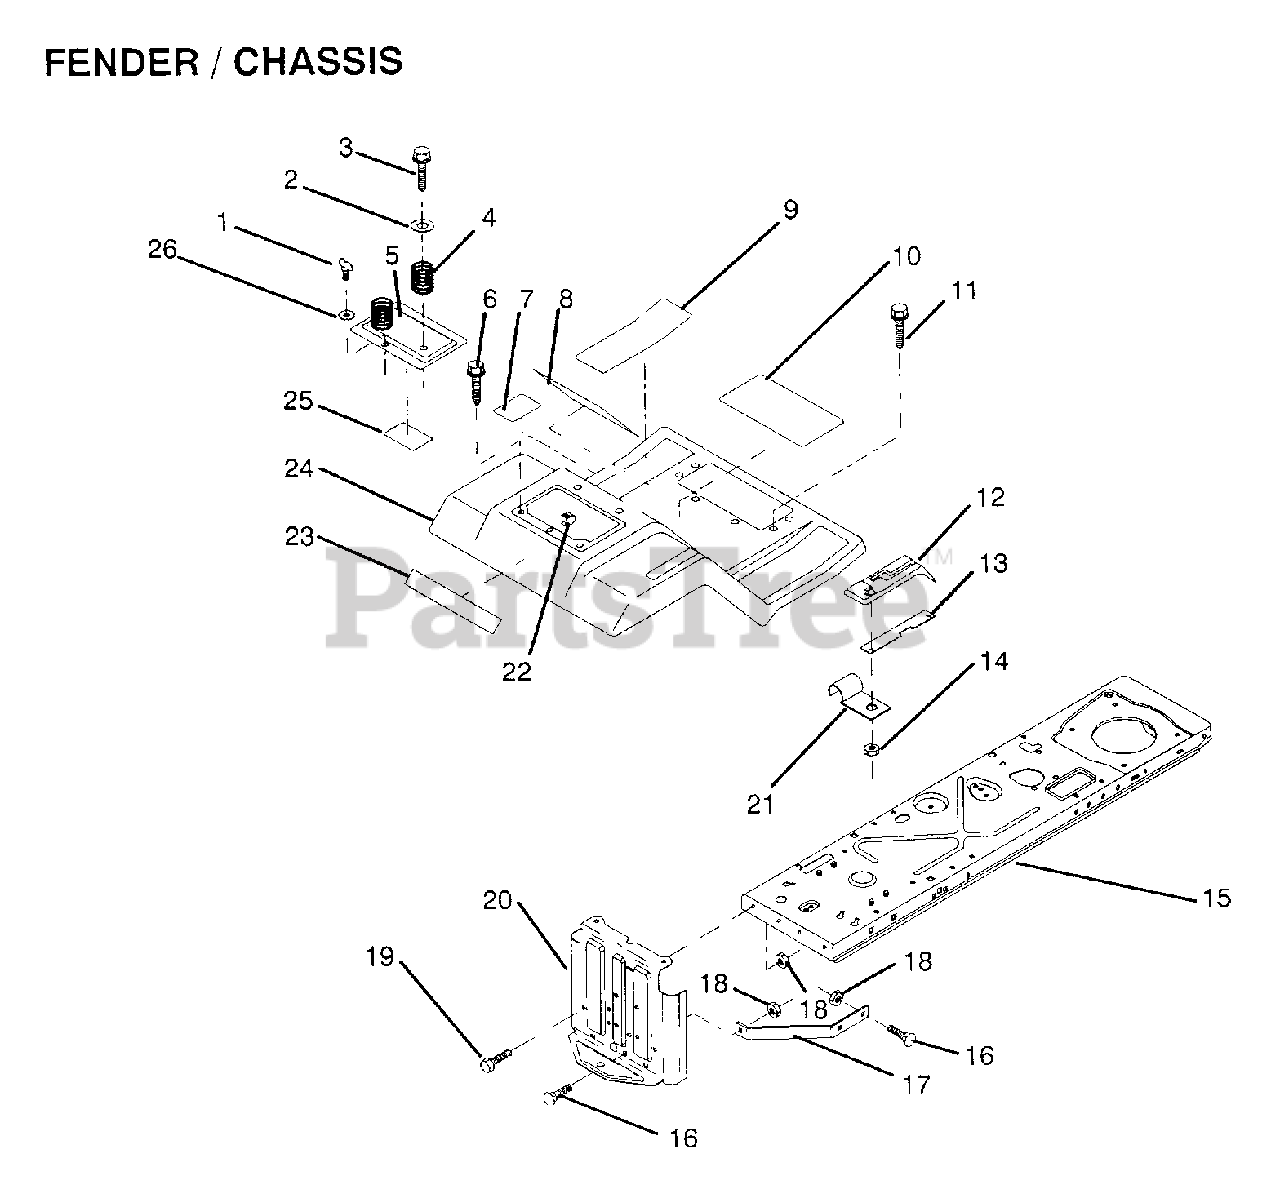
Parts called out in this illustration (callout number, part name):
1	STUD.1/4.TURN
2	WASHER
3	SCREW
4	SPRING COMPRESSIO
6	SCREW LT
7	DECAL DRIVE
8	DECAL
10	DECAL
11	SCREW
12	CONSOLE SHFT 4SP
14	NUT
15	FRAME ASS'Y
16	BOLT
17	"BRACE,DRAWBAR "
19	BOLT
20	DRAWBAR
21	"CLIP,INSULATOR"
22	RECEPTACLE LT
23	DECAL, FENDER
24	"FENDER,FOOTREST"
25	DECAL
26	RETAINER LT
